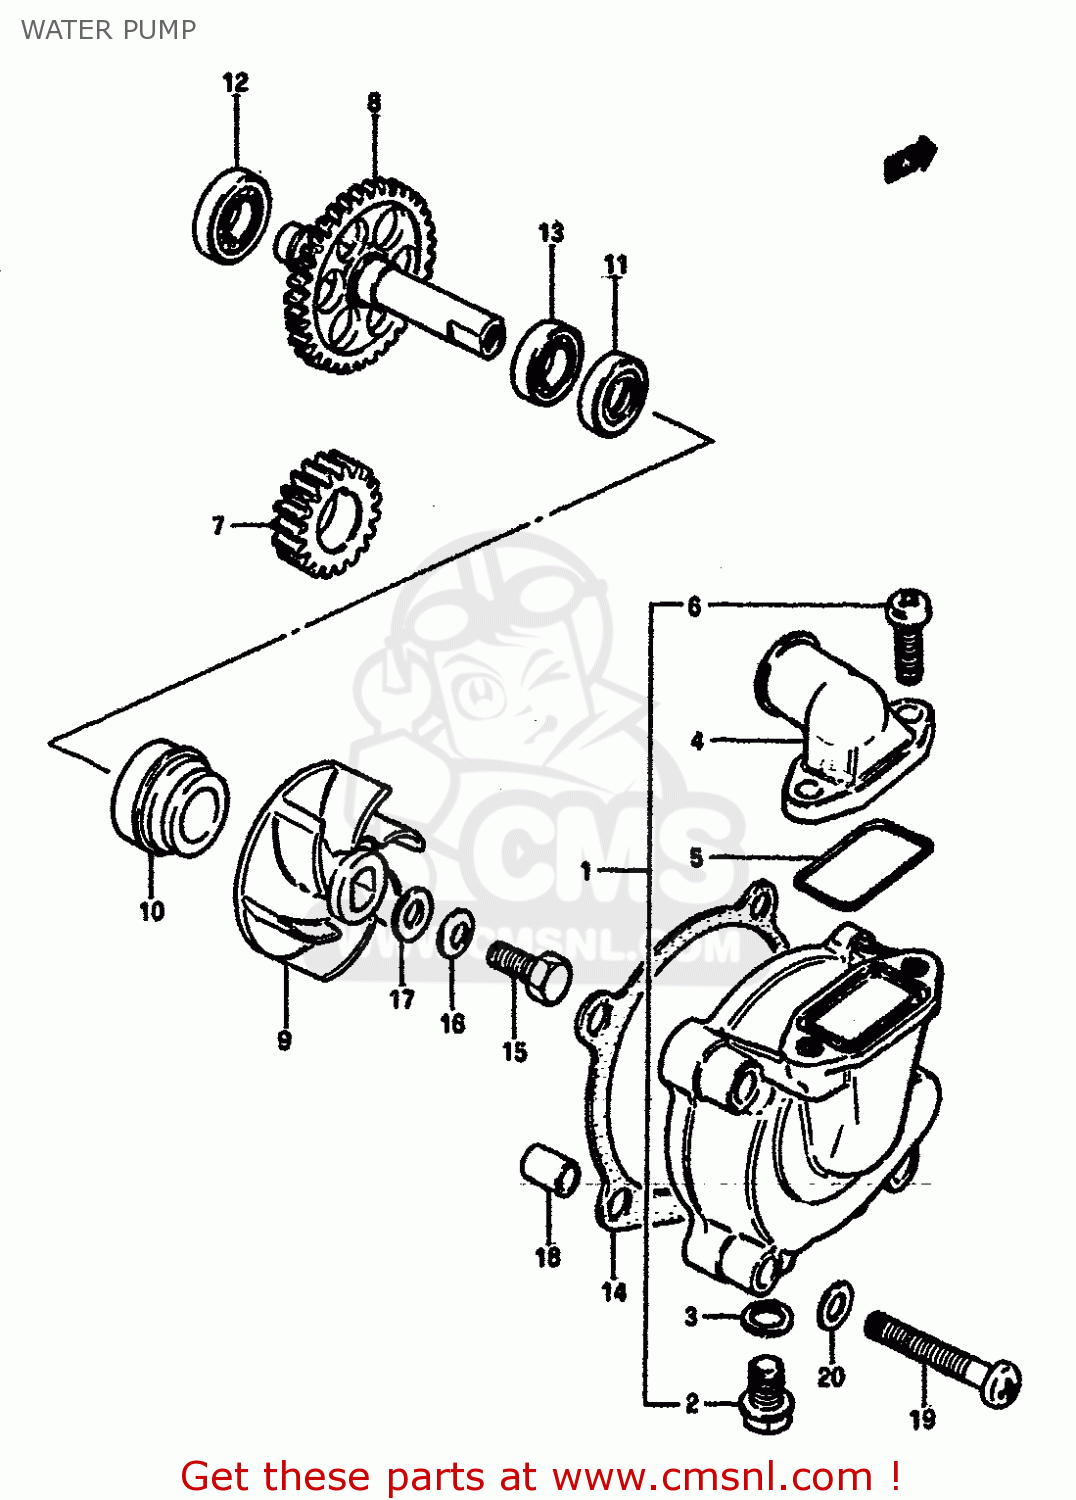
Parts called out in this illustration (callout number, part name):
1	CASE,WATER PUMP
2	BOLT,DRAIN
3	GASKET,DRAIN (NAS)
4	CONNECTOR
5	O RING,WATER PUMP CONNECTOR
6	SCREW
7	GEAR,WATER PUMP DRIVE
8	GEAR,WATER PUMP DRIVEN(NT:36)
9	IMPELLER,WATER PUMP
10	SEAL,WATER PUMP SHAFT
11	SEAL,OIL(10X21X5)
12	BEARING(10X22X6)
13	BEARING
14	GASKET,WATER PUMP CASE (MCA)
15	BOLT(6X13)
16	WASHER
17	GASKET (NAS)
18	PIN
19	SCREW
20	WASHER
